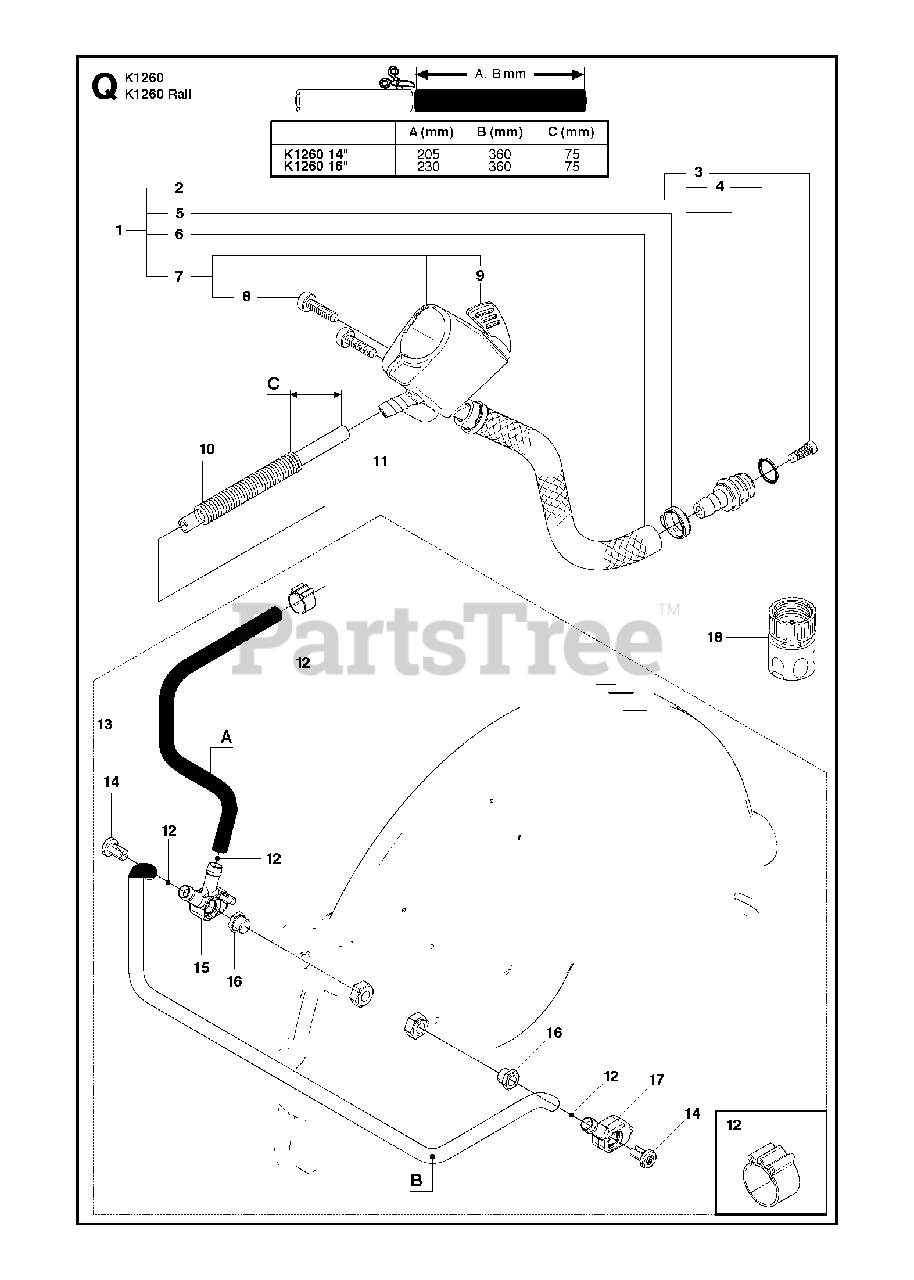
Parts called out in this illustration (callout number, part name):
1	HOSE KITIncl, 2, 5-7
2	NIPPLEIncl. 3, 4
3	FILTER
4	O-RING
5	HOSE CLAMP
6	HOSE
7	VALVE ASSYIncl. 8
8	SCREW ITXSCT
9	VALVE SPINDLE
10	PROTECTIVE SPRING
11	HOSE KIT
13	HOSE620 mm
14	SCREW ITXSCM
18	COUPLERUSA, Canada
